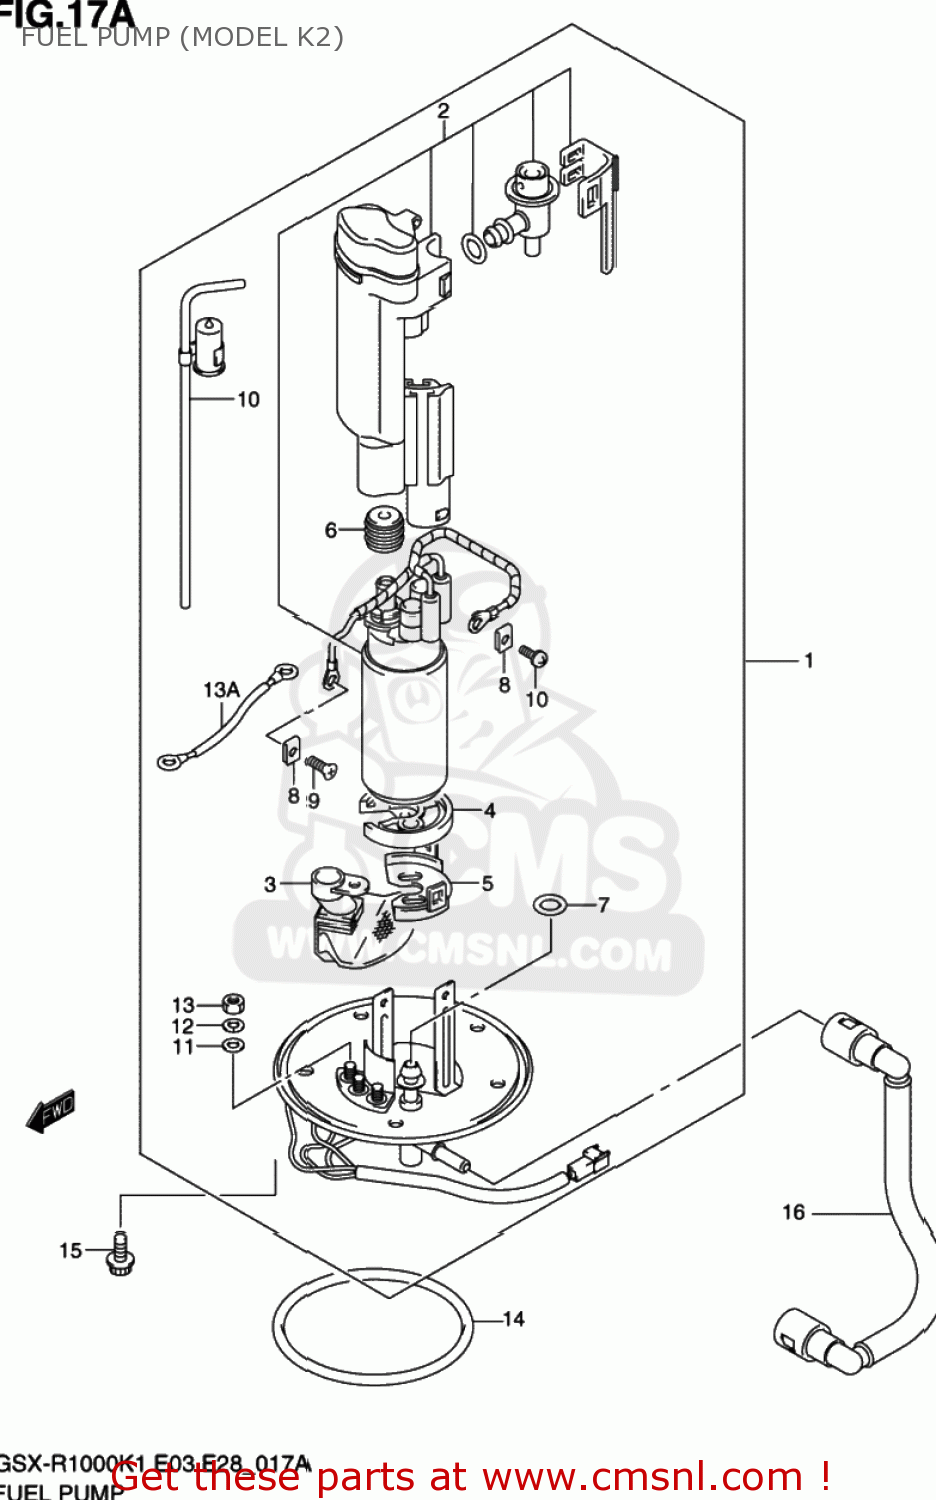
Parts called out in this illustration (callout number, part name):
1	PUMP ASSY,FUEL
2	FILTER ASSY,FUEL
3	STRAINER,FUEL PUMP
4	CUSHION
5	HOLDER,FUEL PUMP
6	BUSH,FUEL PUMP
7	O RING
8	NUT
9	SCREW
10	THERMISTOR
11	WASHER
12	WASHER,SPRING
13	NUT
13A	WIRE
14	O RING,FUEL PUMP
15	BOLT
16	HOSE,FUEL
